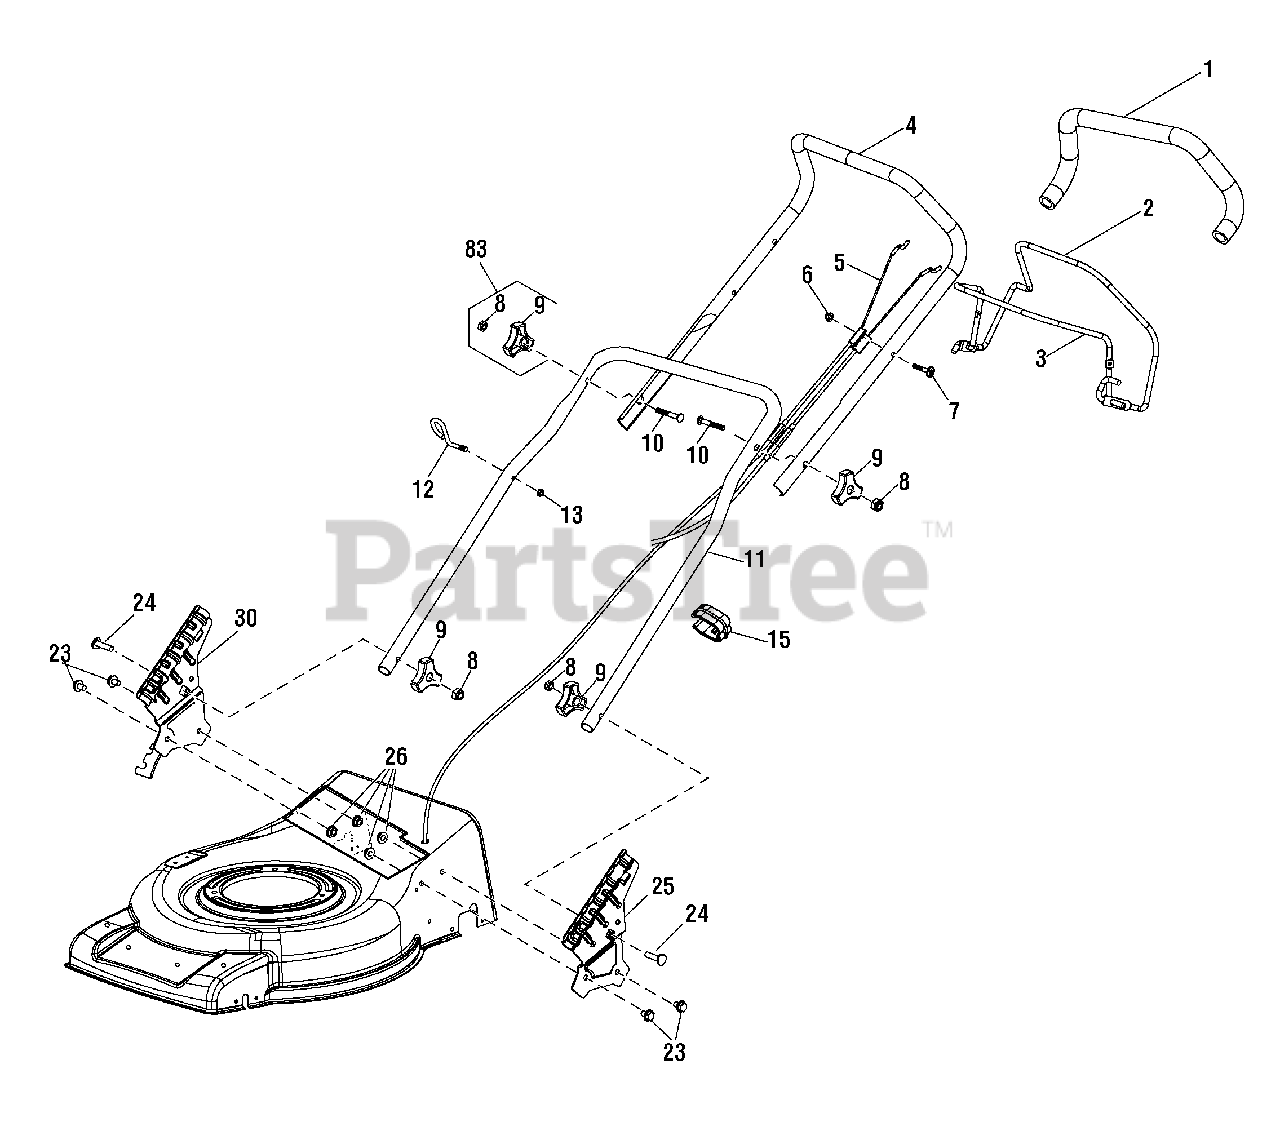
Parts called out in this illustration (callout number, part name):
2	LEVER, Self-propelled Control
3	LEVER, Blade Control
4	HANDLE, Upper
5	CABLE, Clutch
6	ACORN NUT, , M6
7	BOLT, M6x35
8	NUT, M8
10	BOLT, Step, M8 x 45
11	HANDLE, Lower
12	GIUDE, Rope
13	NUT, Self Lock, M6
15	CLIP, Cable
23	BOLT, Hex Flange, M8 x 16
24	BOLT, Arc Head
25	BRACKET, Handle, Left
26	NUT, Hex, Prevailing Torque Type, M8
30	BRACKET, Handle, Right
83	HANDLE KNOB ASSEMBLY
